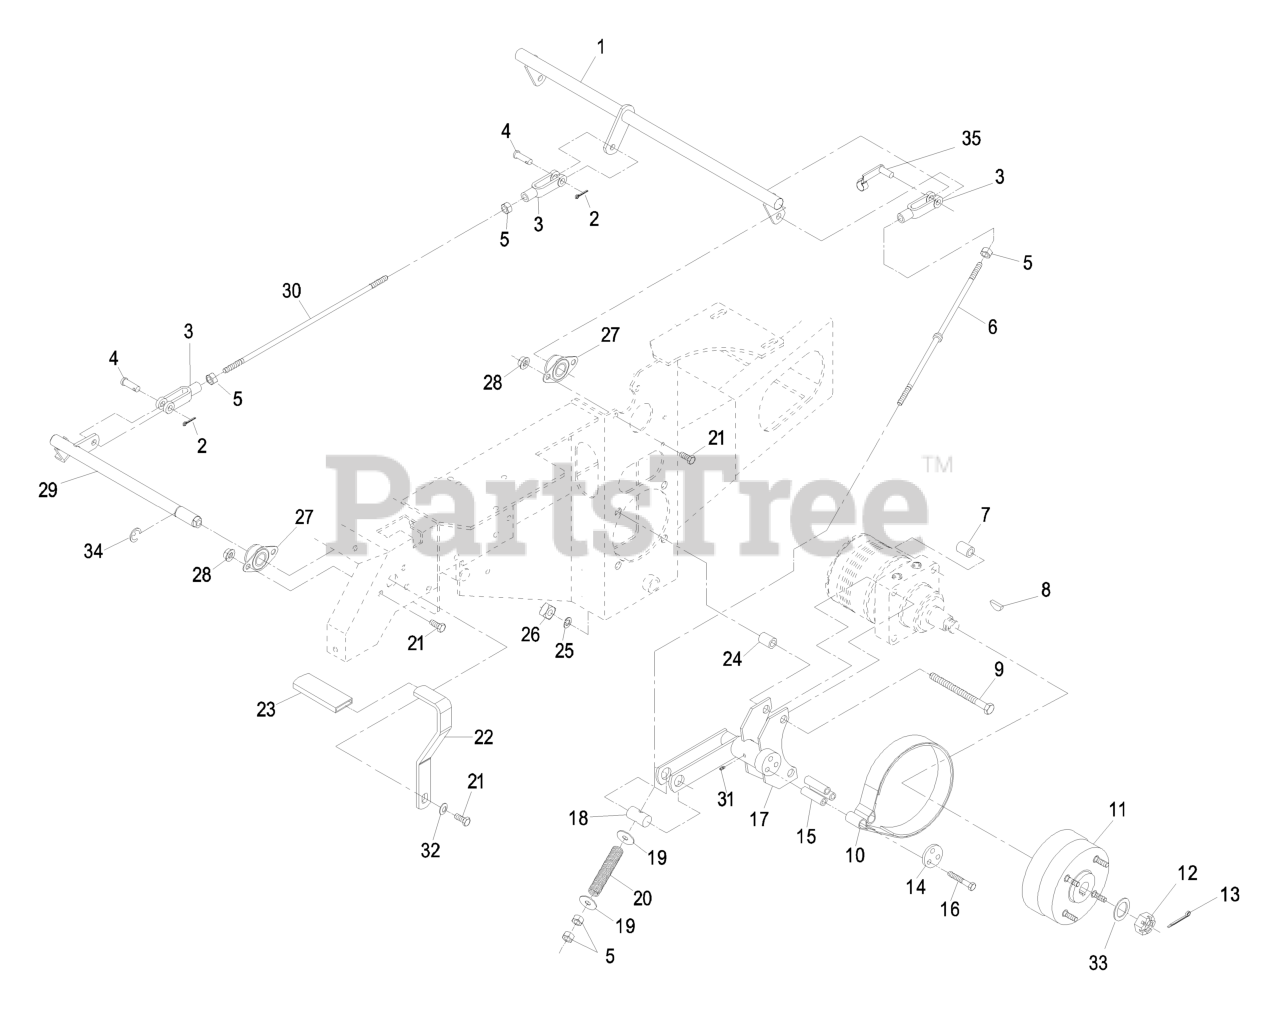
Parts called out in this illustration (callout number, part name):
1	CRANK-BRAKE, PARK
2	PIN-COTTER
3	YOKE-LINKAGE, BRAKE
4	PIN-CLEVIS
5	NUT-HEX
6	ROD-BRAKE
7	SPACER-WHEEL
8	KEY-WOODRUFF
9	SCREW-HH
10	BAND,BRAKE
11	WHEEL HUB ASM
13	PIN-COTTER
14	RETAINER-BAND, BRAKE
16	SCREW-HH
17	BRACKET-BRAKE
18	PIN-TRUNION
19	WASHER-FLAT
20	SPRING-BRAKE
21	SCREW-HH
22	ASM,BRAKE HANDLE W/ GRIP
23	GRIP-LEVER
24	SPACER-WHEEL
25	WASHER-LOCK
27	BEARING-FLANGE, SIDE
28	NUT-HHF, WHIZ
29	SHAFT-BRAKE, PARKING
30	LINKAGE-HANDLE, BRAKE
31	FITTING-GREASE
32	WASHER-BELLEVILLE
33	WASHER-SPACER
35	PIN-SPRING, CLEVIS
